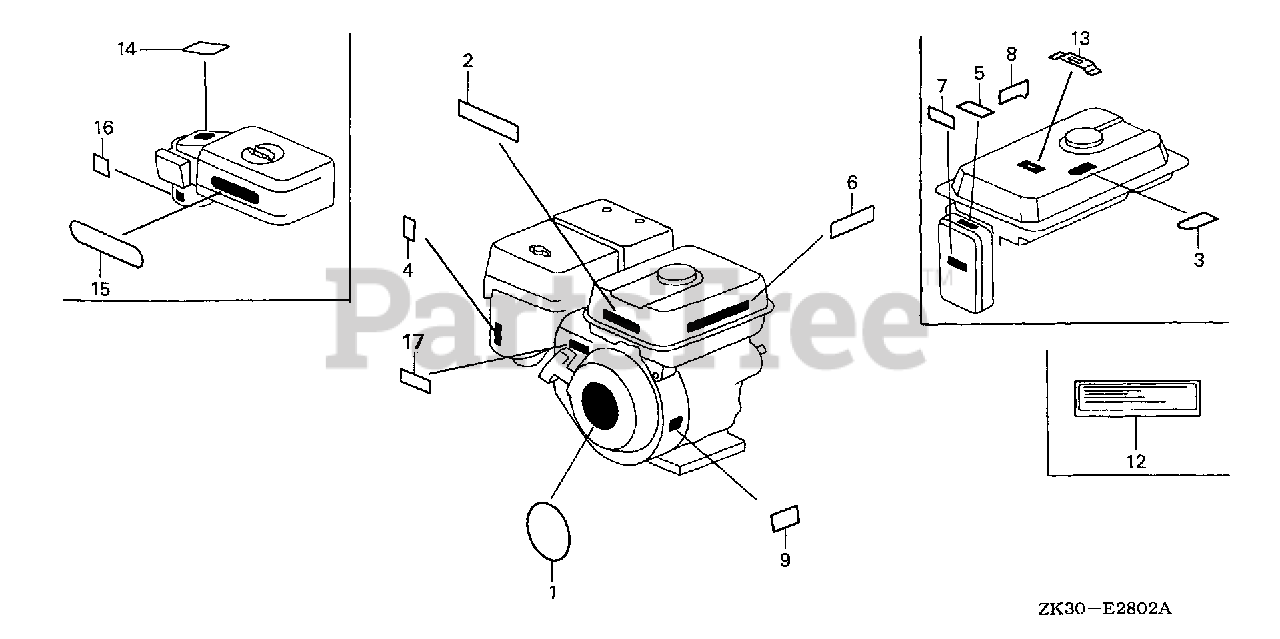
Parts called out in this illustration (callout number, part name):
1	EMBLEM (11. (HONDA)
2	LABEL, CAUTION (ENGLISH, ETC.)
4	MARK, CHOKE (ORANGE)
6	MARK, OIL ALERT (GERMAN)
6	MARK, OIL ALERT (FRENCH)
6	MARK, OIL ALERT (ENGLISH)
9	MARK, OIL ALERT (ENGLISH)
